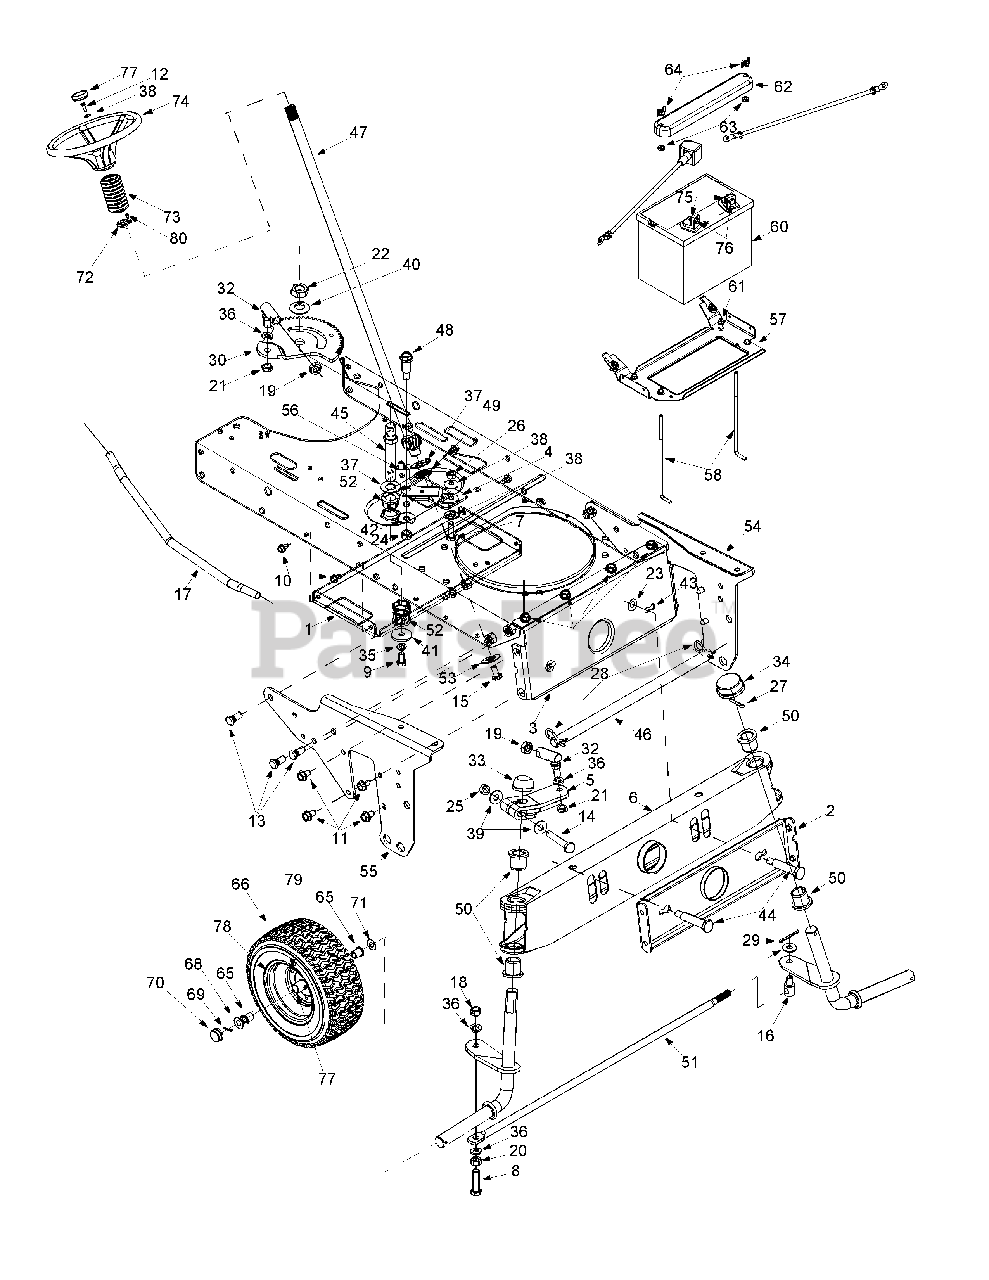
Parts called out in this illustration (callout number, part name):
7	Hex Bolt 5/16-24 x 1.0"
8	Hex Bolt 3/8-24 x 1.50"
9	Hex Bolt 5/16-18 x 0.625"
10	TT Screw 1/4-20 x 0.5"
11	TT Screw 5/16-18 x 0.625"
12	Hex Bolt 5/16-18 x 1.0"
13	Rib Neck Rd. Bolt
14	Hex Bolt 3/8-24 x 2.5"
15	Pan Hd. Machine Screw
16	Ferrule
17	Steering Drag Link
18	Hex Lock Nut 3/8-24
19	Jam Nut
20	Hex Nut 3/8-24
21	Lock Nut
22	Jam Nut
23	Flange Lock Nut
24	Hex Nut 3/8-16
25	Lock Nut
26	Hex Nut
27	Cotter Pin
28	Hairpin Clip
29	Cotter Pin
30	Steering Gear Segment: 25T
32	Ball Joint
33	Push Cap
34	Hub Cap
35	Lock Washer
36	Lock Washer
37	Flat Washer
38	Beleville Washer
39	Flat Washer
40	Bell Washer
41	Flat Washer
42	Bell Washer
43	Grease: Alvania (TM)
44	Shoulder Screw
45	Steering Gear Shift Segment
46	Deck Rod
47	Steering Shaft
48	Shoulder Screw
49	Hex Flange Bearing
50	Flange Bearing
51	Tie Rod
52	Hex Flange Bearing
53	Cap
60	Battery
61	Hex Washer B-Tap Scr.
62	Battery Cover
63	Hex Nut
64	Wing Nut
65	Flange Bearing
66	Wheel
68	Flat Washer
69	Cotter Pin
70	Hub Cap
71	Flat Washer
72	Flange Bearing (Style A only)
73	Steering Bellow (Style 0, 3,5,9)
74	Steering Wheel
75	Hex Lock Nut
76	Hex Bolt 1/4-20 x .75"
77	Steering Cap (Round)
79	Air Valve
80	Oval Hd. C-Sunk Screw
81	Pivot Bar Cap End
82	Grease
83	Axle Assembly LH: Front
